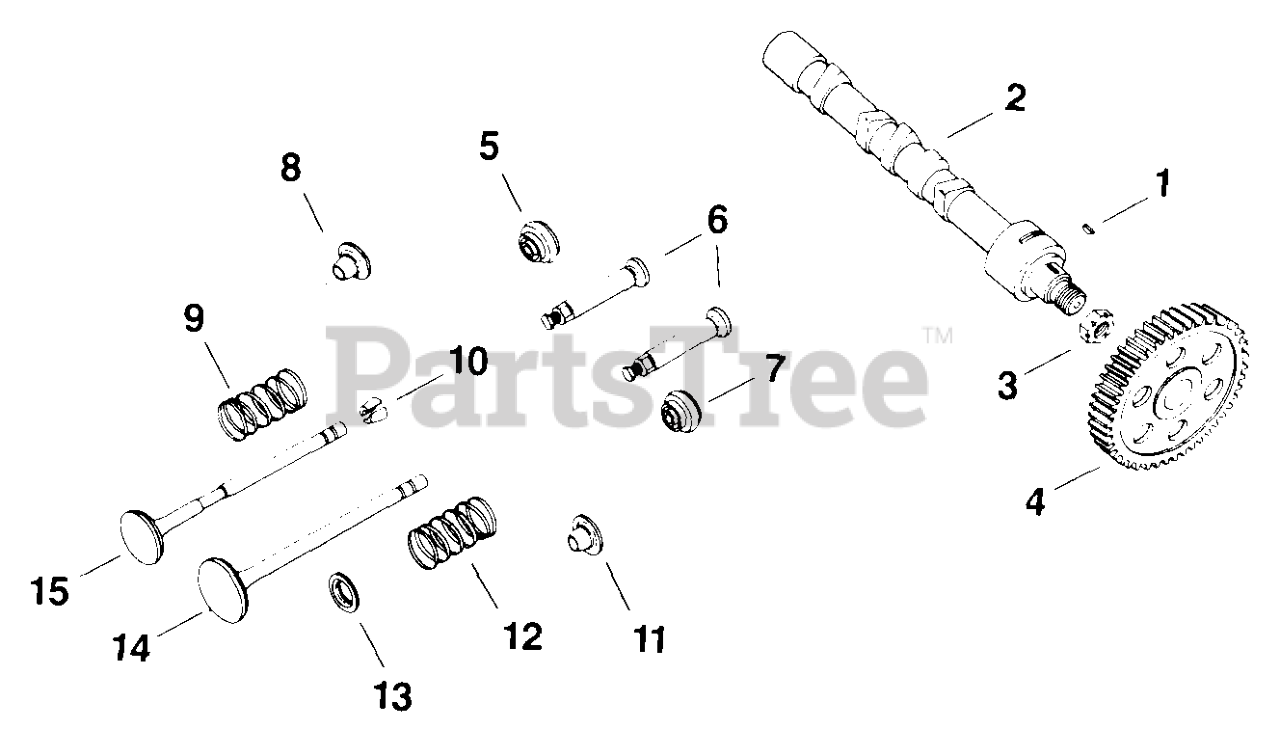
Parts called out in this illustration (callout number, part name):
1	KEY, 1/8" X 1/2"
4	KIT - USE 48 755 34
5	ROTATOR - USE 52 413 01
6	TAPPET - DISCONTINUED
9	SPRING, INTAKE VALVE - DISCONTINUED
10	KIT, RETAINER
11	RETAINER, VALVE SPRING
12	SPRING, EXHAUST VALVE-(#DSC)
13	RETAINER, SPRING
14	VALVE, INTAKE - DISCONTINUED
15	VALVE, EXHAUST
